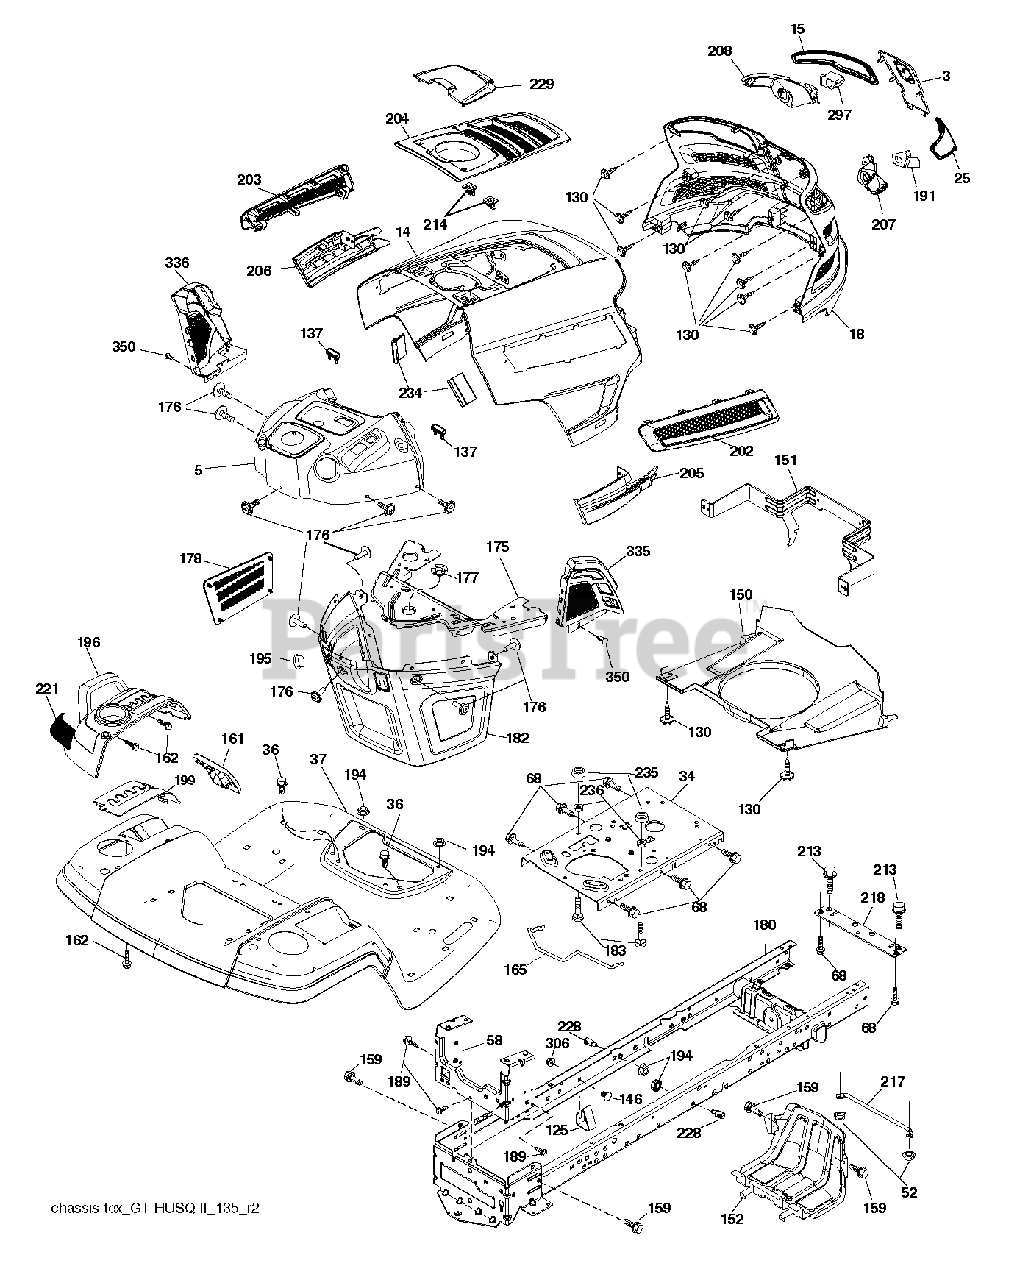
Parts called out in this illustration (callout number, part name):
3	APPLIQUE.SUBASM.GT.HUSQ.II
14	HOOD.ASM.HUSQVARNA.GT.TEX.ORAN
15	LENS.HEADLIGHT.LH.GTII.2011
18	GRILLE.SUBASM.GT.HUSQ.II
25	LENS.HEADLIGHT.RH.GTII.2011
34	PLATE.ENGINE.WELDED.CHASSIS
36	SCREW 5/16"
37	FENDER.PNT.TX.GT.CH/FW/DL.HUSQ
52	LOCKNUT
58	DRAWBAR.UPPER.2PC,LRG.FENDER
68	SCREW LT
125	CLIP.FUEL.LINE
130	SCREW.#10 X 0.750.BOS
137	BUMPER DASH
146	BOLT.RDHD.SHT.SQNK.3/8-16X5/8
150	AIR DUCT.GTV2(1.66"RING HEIGHT
151	BRACKET.PIVOT.HOOD.GT.HUSQ.II
152	SHIELD.BROWNING.PNT.GT.V2
159	SCREW, 3/8-16X3/4
161	CONSOLE.WINDOW.FUEL.HUSQ.GT
162	SCREW.HI-LO.CONSOLE
165	SUPPORT.TANK.REAR.W/TEX
175	PLATE.CROSSMEMBER.HUSQ
176	SCREW.#10-24X5/8.RN.QU
177	BUSHING, STEERING
178	CARGO.ASM.NET.TXGT.W/C
180	CHASS.WLDMNT.TLT.12GA/2PC.20"
182	DASH.LOWER.COMMON.12V.ADAPTOR
183	BOLT.5/16-18X1-1/4 FULL THD
189	SCREW
191	INSERT.REFLECTIVE.RH.HUSQ.GTII
194	NUT LOCK HEX FLANGE 5/16-18
195	PLUG.HOLE.DASH.LOWER.12V.BLK
196	SUBASM.CONSOLE.HUSQ.GT.DECKLFT
199	PLATE.DECK.LIFT.HUSQVARNA.GT
202	VENT.SIDE.RH.GT.HUSQ.II.
203	VENT.SIDE.LH.GT.HUSQ.II.498
204	VENT.TOP.EXTERNAL.FILL.GT2.GRE
205	SIDE.TRIM.RH.GT.HUSQ.II
206	SIDE.TRIM.LH.GT.HUSQ.II.GRAY
207	BEZEL LIGHT.RH.GT.II.MYLAR
208	BEZEL LIGHT.LH.GT.II.MYLAR
213	BOLT
214	CLIP.RETAINER.TINNER.
217	ROD.PIVOT.HOOD
218	X-PIECE.HOOD.STOP.NON/
221	REFLECTOR.LH.TEX GT HU
228	STUD.FASTNER.W/ANTI-ROTATE
229	LID.EXT.FILL.GT.HUSQ2.BLACK
234	BUMPER.HOOD.TEX.HUSQVARNA
235	SPACER FENDER
236	NUT.CENTERLOCK.5/16-
297	INSERT.REFLECTIVE.LH.HUSQ.GTII
306	NUT LOCK FLG 3/8-16 UNC
335	COVER.LOWER.DASH.RH.BLACK
336	COVER-LH.LOWER.DASH.GT2.BLACK
350	CLIP.X-MAS.TREE
